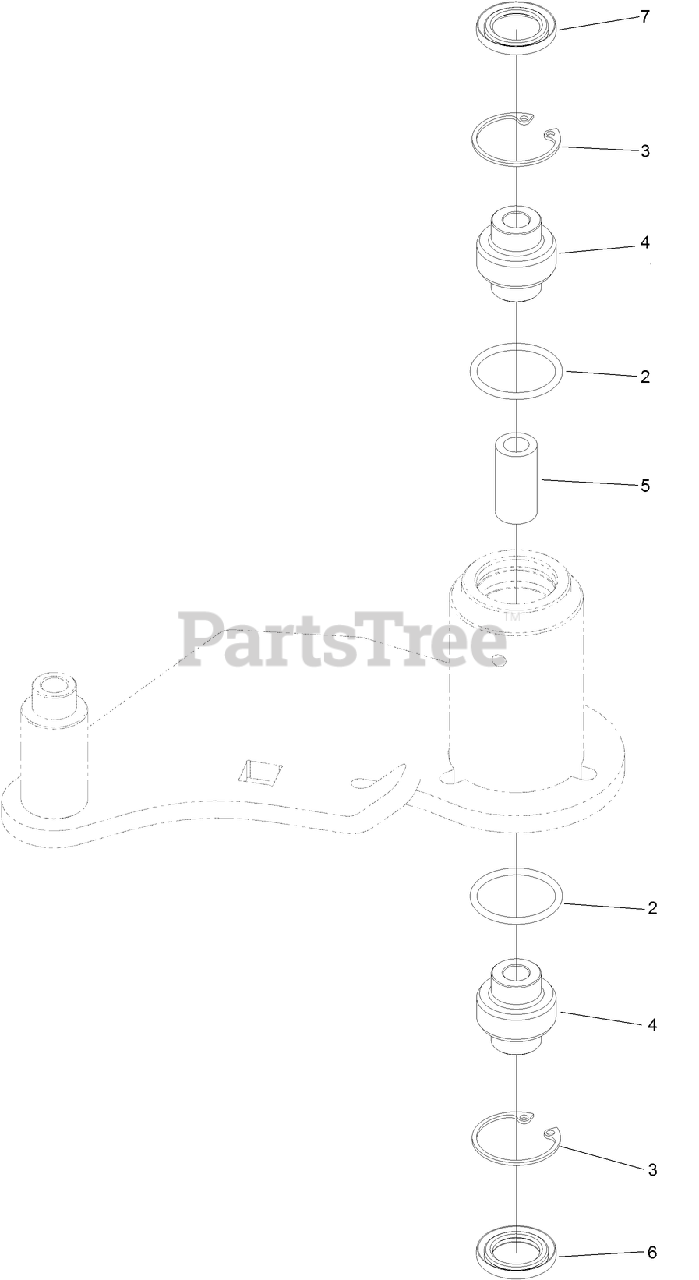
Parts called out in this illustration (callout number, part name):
2	O-RING
3	RING-SNAP
4	BEARING-SPHERICAL
5	SPACER
6	Seal-Lip, Double
7	SEAL-LIP, SINGLE
